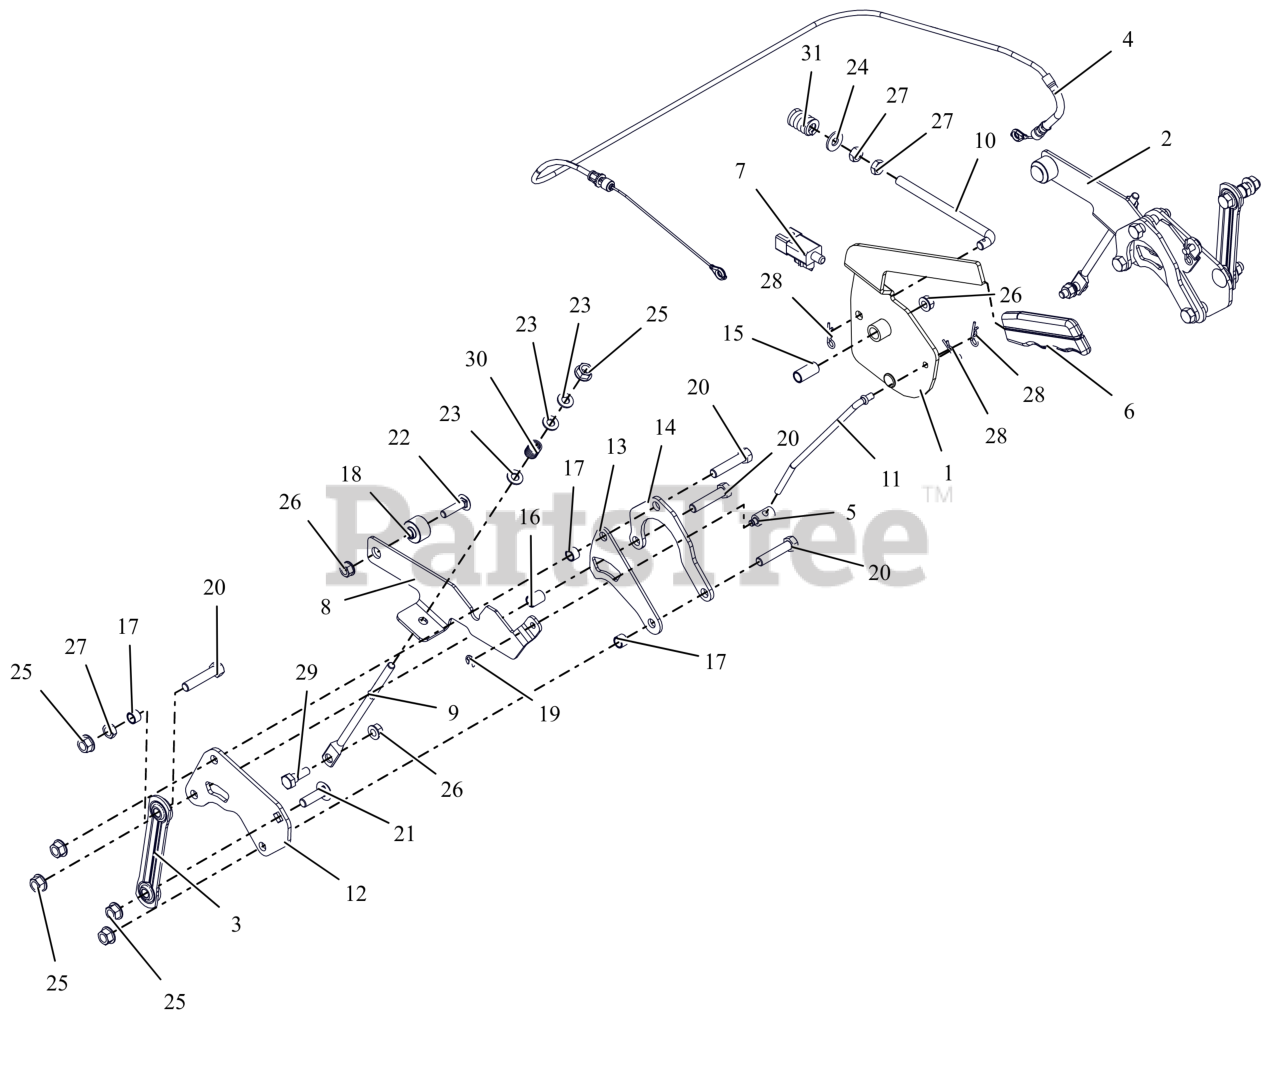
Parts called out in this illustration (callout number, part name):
1	LEVER, PARKING BRAKE
2	ARM, BRAKE - LH (W/PIN)
3	LINK, STAMPED STEERING
4	CABLE, BRAKE - PARKING
5	TRUNION, 1/4-20
6	GRIP, PARKING BRAKE (YELLOW)
7	SWITCH, SNAP IN - N.O./N.O.
8	ARM, BRAKE-RH
9	ROD, LINK - TRANSMISSION BRAKE
10	ROD, OVER CENTER
11	ROD, BRAKE LINK
12	BRKT, TRANSAXLE STEERING
13	BRKT-SPACER
14	PLATE, REAR REINFORCING
15	BSHG-SLV .385X.500X1.045
16	SPCR, SLV .385X.500X.652
17	SPCR, SLV .385X.500X.350
18	SPCR, FLANGE
19	RG-RTNG-EXT .250X.025
20	BLT, HEX .38-16X1.75 G5 ZCC
21	BLT,RHSSN .38-16X1.25 G5 ZCC
22	BLT, RHSSN.31-18X1.25 G5 ZCC
23	WSHR,FLT .344X.688X.065 ZCC
24	WSHR,FLT .375X.875X.083 ZCC
25	NUT-LK-TOP-FLG .38-16 ZC120
26	NUT-LK-TOP-FLG .312-18 GF ZCC
27	NUT-JAM .375-16 G2 ZCC
28	PIN, HAIR #213 .08X1.19 ZCC
29	BOLT,SHLDR .38X.25 -.31-18X.75
30	SPRING, COMPRESSION
31	SG-COMP .187X.56X1.62
